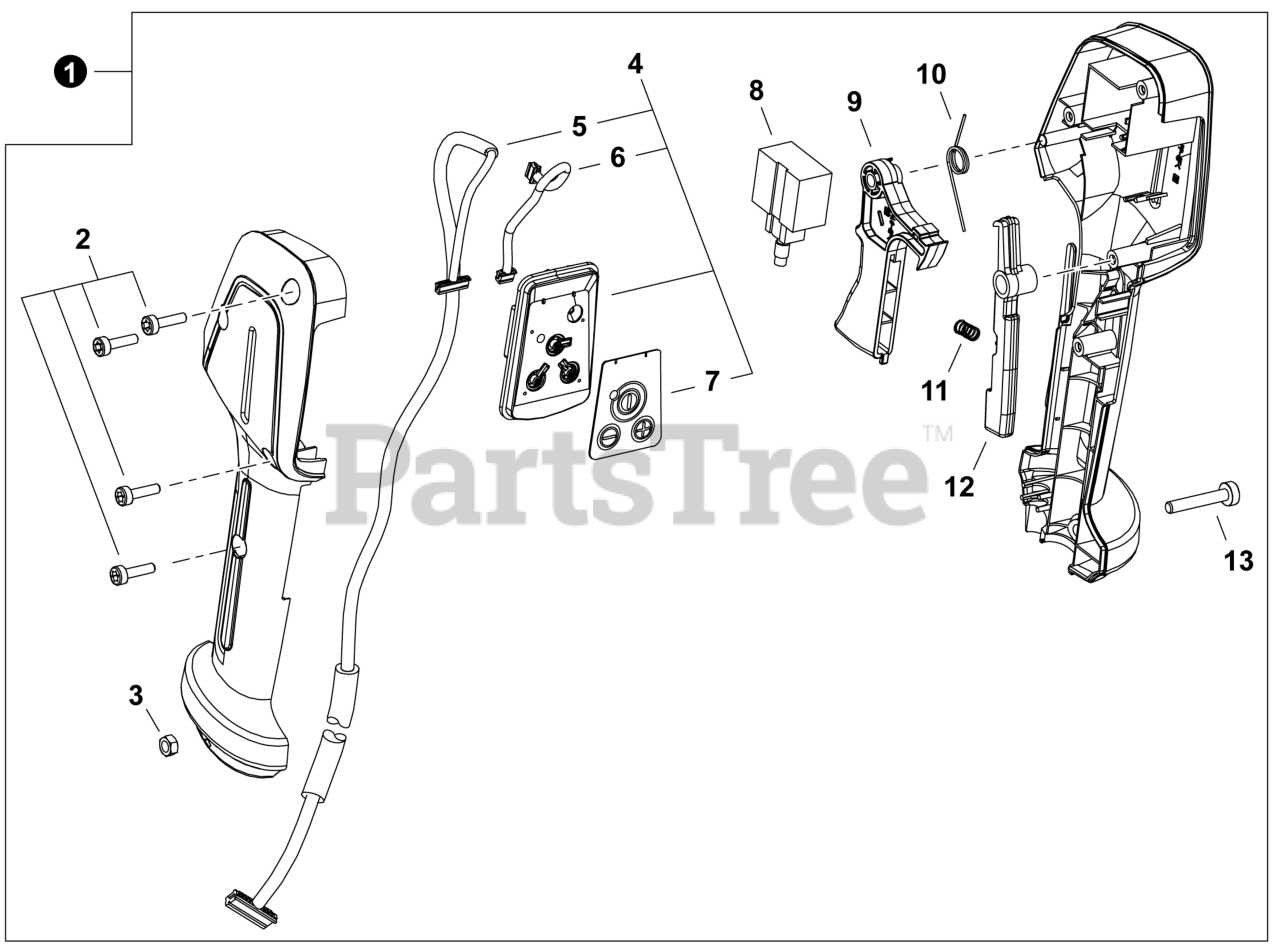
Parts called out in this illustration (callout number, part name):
1	CONTROL HANDLE ASSY
2	BOLT, TORX 4x16
4	SWITCH ASSY, ON-OFF
5	WIRE HARNESS - MAIN
6	WIRE HARNESS - TRIGGER
7	LABEL - SWITCH
8	SWITCH, SPEED CONTROL
9	TRIGGER, THROTTLE
10	SPRING, TORSION
11	SPRING, COIL
12	LOCKOUT, THROTTLE
13	BOLT, TORX 5x30
